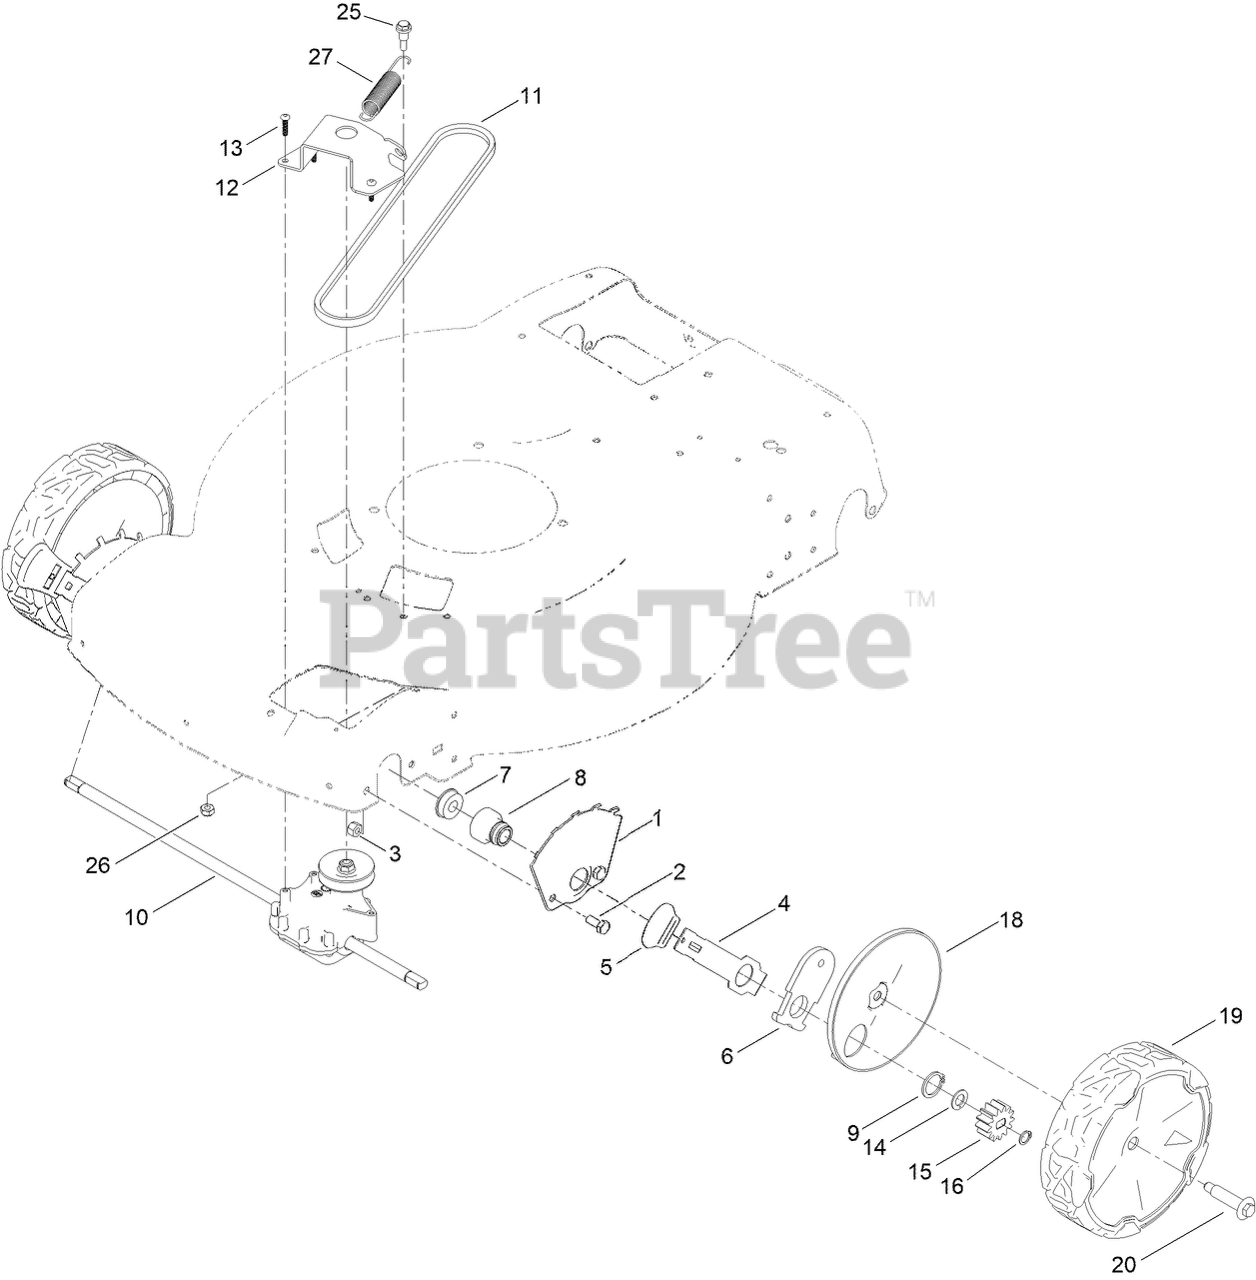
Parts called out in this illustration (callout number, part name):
1	PLATE-HOC,FRONT FSVQ WEDNESDAY
2	SCREW-HH
3	NUT-LOCK, NI
4	ARM-SPRING
5	KNOB-HOC
6	ARM-PIVOT, FRONT
7	BEARING-BALL
8	RETAINER-BEARING, HOC
9	RING-RETAINING
10	TRANSMISSION
11	V-BELT
12	BRACKET-TRANSMISSION
13	SCREW-PLASTITE
14	WASHER-THRUST
15	GEAR-PINION, 13T
16	RING-RETAINING
18	ASM-COVER, WHEEL (DK GRAY)
19	ASM-8" WHEEL, FWD (BUSHINGS)
20	WHEEL BOLT
25	BOLT-SHOULDER
26	NUT-LOCK, NI
27	SPRING-EXTENSION
